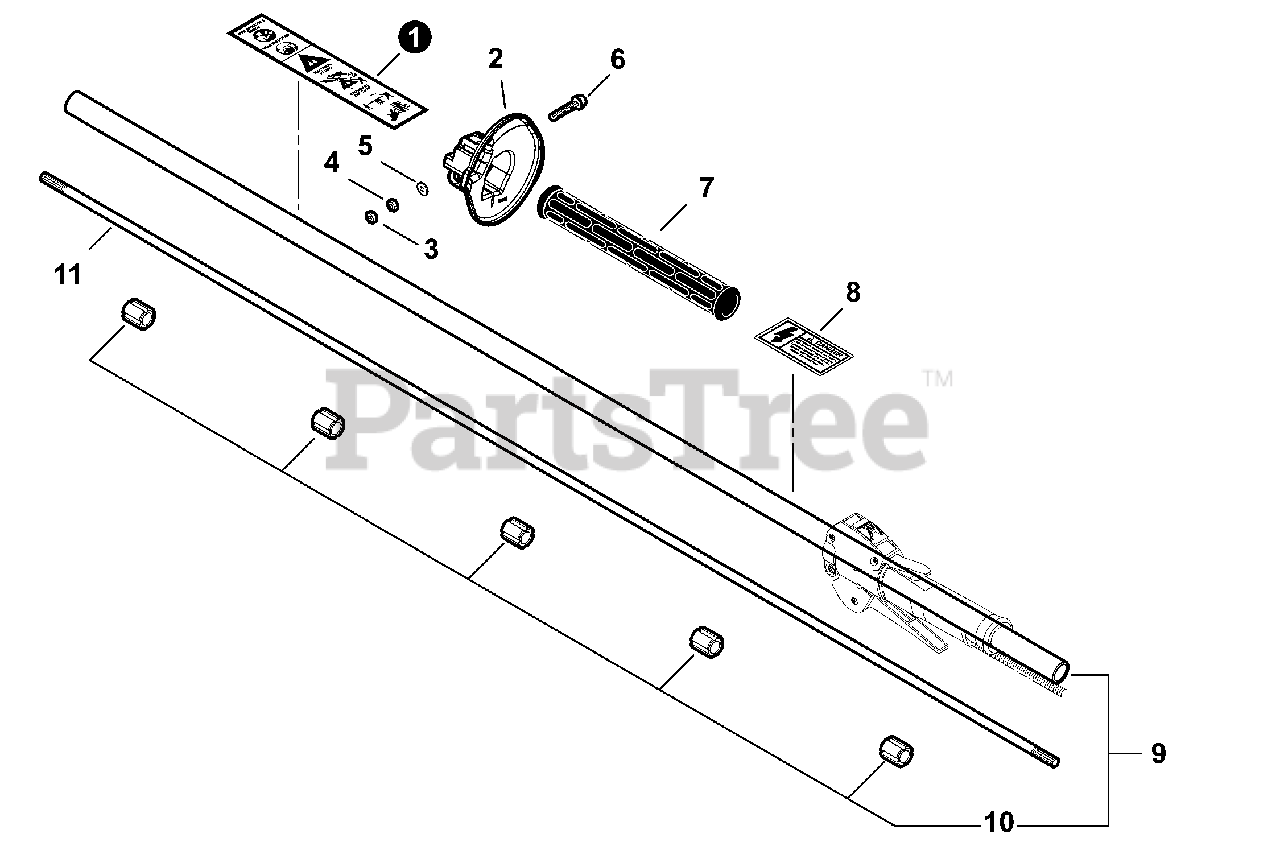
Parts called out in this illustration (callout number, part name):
1	LABEL, CAUTION
2	GUARD, HAND
3	NUT, LOCK
5	WASHER 5.5×12×0.8
6	SCREW - 5×35
7	GRIP, FRONT
8	LABEL, HIGH VOLTAGE
9	MAIN PIPE ASSY
10	BUSHING
11	MAINSHAFT
